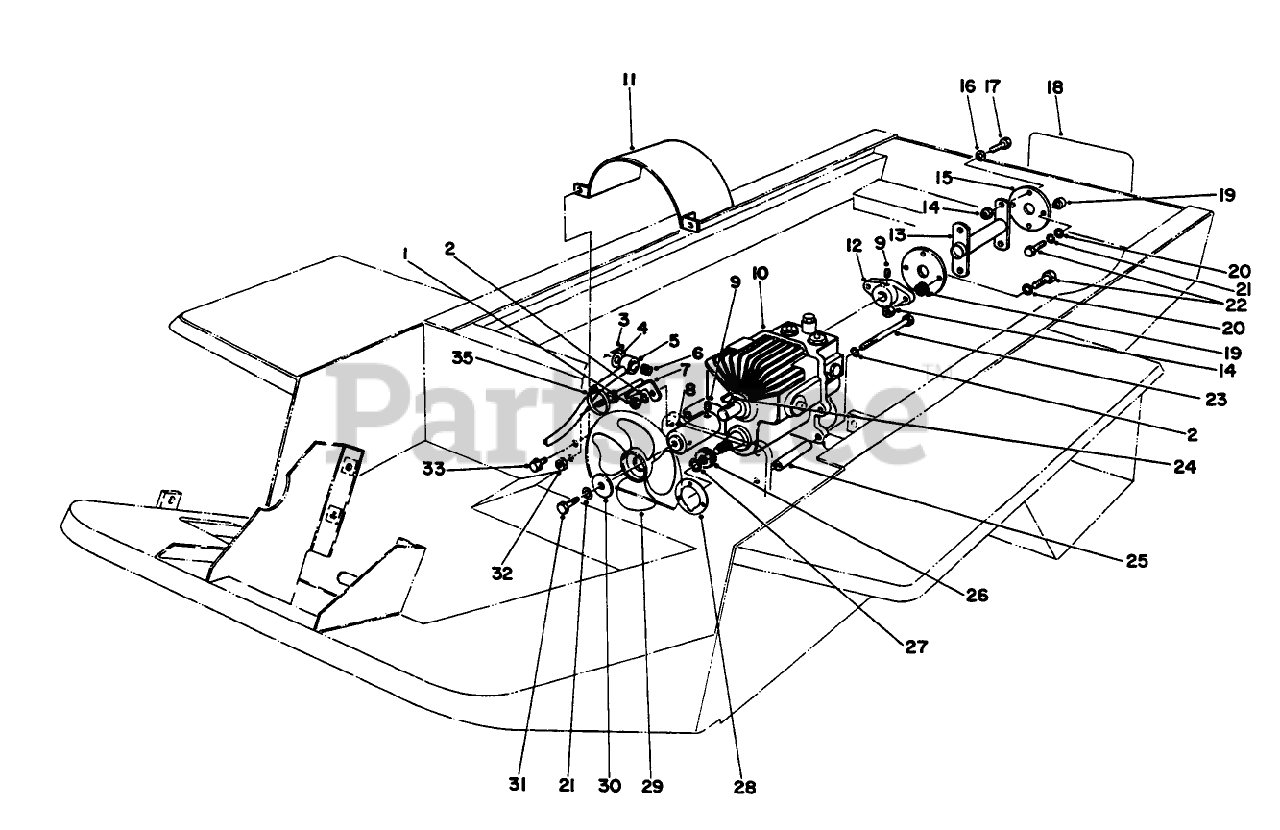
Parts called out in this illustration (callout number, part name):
1	NUT-HEX
2	WASHER-LOCK
3	PIN-COTTER
4	WASHER-FLAT
5	PUMP CONTROL TUBE WA
6	BUSHING-RUBBER
7	Axle Support
8	Hub & Plug
9	SCREW-SET, HSH
10	Transmission
11	Fan Shroud
12	Hub-Pump
13	Drive Shaft
14	NUT-HEX
15	COUPLING-RUBBER
16	SPACER-COUPLING
17	SCREW-HH
19	SPACER-RUBBER COUPLNG
20	WASHER-FLAT
21	WASHER-LOCK
22	SCREW-HH
23	SCREW-HH
24	KEY-WOODRUFF
25	SPACER-MOUNTING
26	GEAR-PINION
27	Ring-Snap
28	GASKET-TRANSMISSION
30	WASHER
31	SCREW-HH
32	NUT-JAM
33	SCREW-HHF
35	TIE-CABLE
